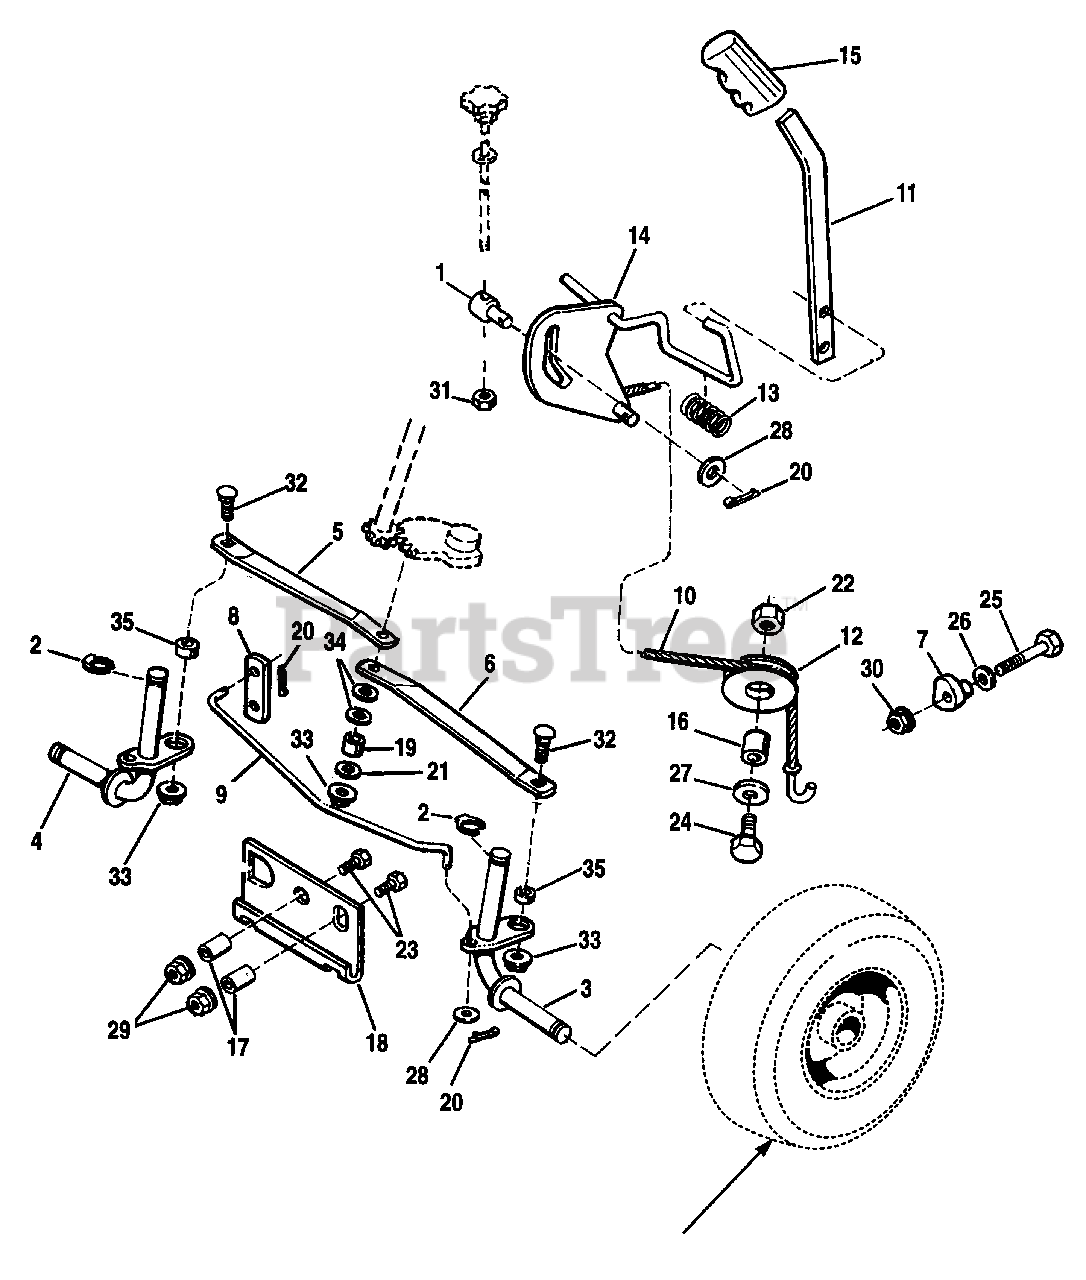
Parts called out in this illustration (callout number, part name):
3	SPINDLE ASSY., LH
4	SPINDLE ASSY., RH
5	TIE ROD, RH
6	TIE ROD, LH
10	CABLE ASSY., Lift
11	LEVER, Lift
12	PULLEY, Lift
13	SPRING, Compression
14	ARM ASSY., Lift
15	GRIP, Lever
18	HITCH, Hook
19	SPACER, 21/64 x 1/2 x 5/8
20	COTTER PIN, 3/32 x 3/4
21	WASHER, Plain, 11/32 x 1 x 1/8
22	NUT, Hex, Esna Lock, 3/8-16
23	CAPSCREW, Hex Hd., 1/2-13 x 1-1/2
24	CAPSCREW, Hex Hd., 3/8-16 x 1-1/2
25	CAPSCREW, Hex Hd., 3/8-16 x 1-3/4
26	WASHER, Plain, 13/32 x 7/8 x 1/8
27	WASHER, Plain, 13/32 x 1-1/2 x 1/8
28	WASHER, Plain, 13/32 x 7/8 x 5/64
29	NUT, Hex, Flange Lock, 1/2-13
30	NUT, Hex, Flange Lock, 3/8-16
31	NUT, Hex, 3/8-16
32	CARRIAGE BOLT, 3/8-16 x 1
33	NUT, Hex, Flange Lock, 5/16-18
34	WASHER, Plain
